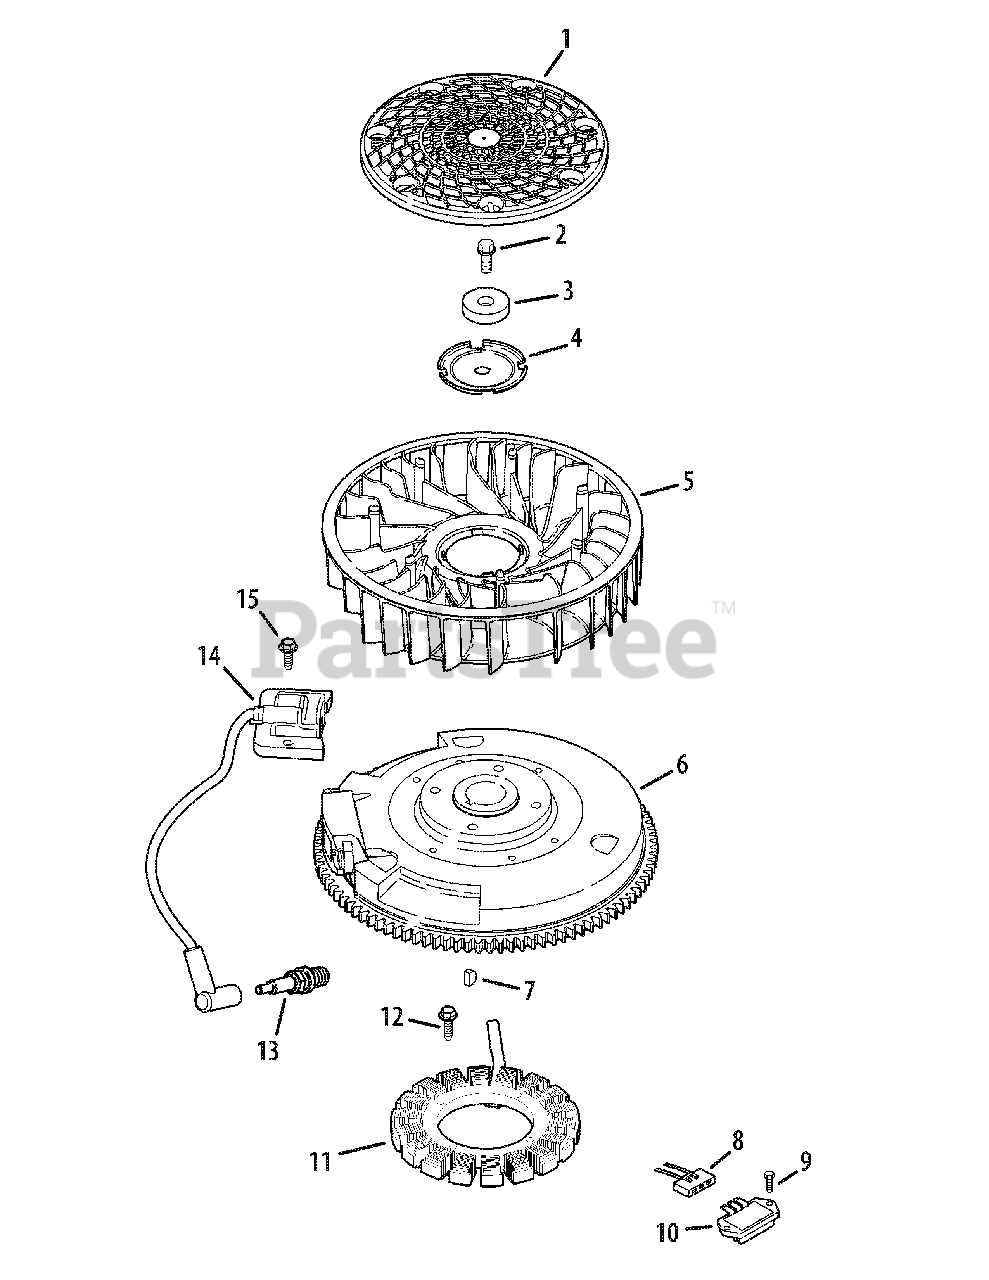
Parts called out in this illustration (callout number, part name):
1	Screen, grass
2	Screw, hex. flange M10x1.5x45
3	Washer, plain 3/8"
4	Plate, fan mounting
5	Fan
6	Flywheel
8	Connector
9	Screw, heavy hex. flange M5x0.8x16
10	Rectifier-regulator
11	Kit, 15 amp stator
12	Screw, hex. head M5x0.8x25
13	Spark plug
14	Module, ignition
15	Screw, hex. flange M5x0.8x20
KH-M448010-S	Screw
